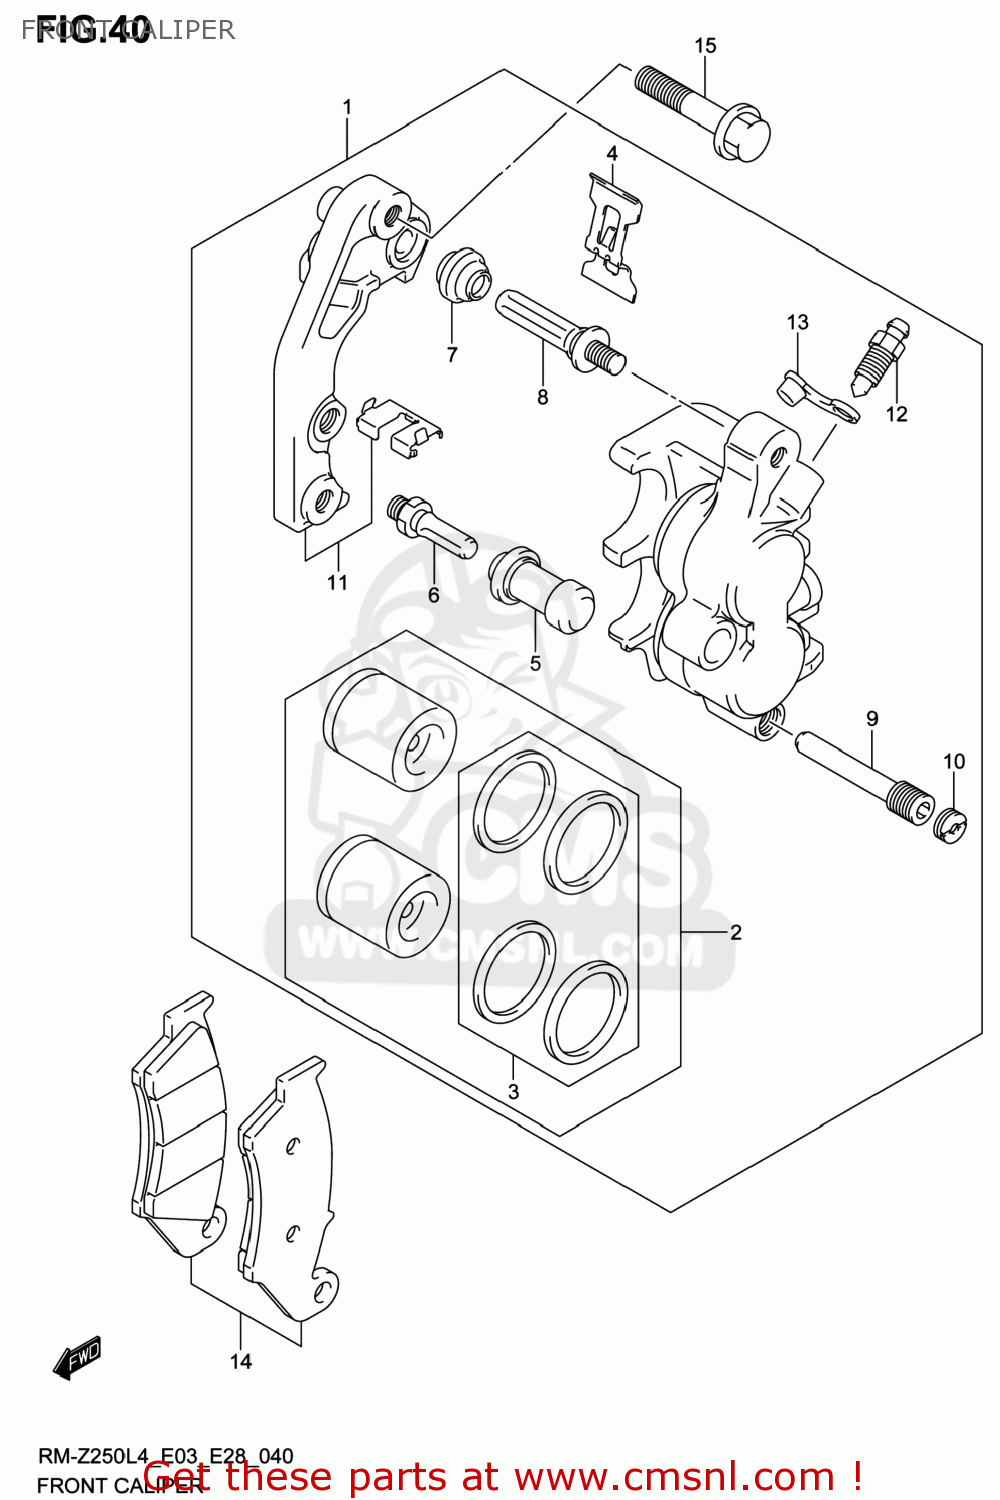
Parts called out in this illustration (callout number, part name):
1	CALIPER ASSY,FR
2	PISTON SET
3	SEAL SET,PISTON
4	SPRING,PAD
5	BOOT
6	BOLT
7	BOOT
8	PIN
9	PIN,HANGER
10	PLUG,PIN
11	BRACKET
12	BLEEDER
13	CAP,BLEEDER
14	PAD SET (NAS)
15	BOLT(8X41)
